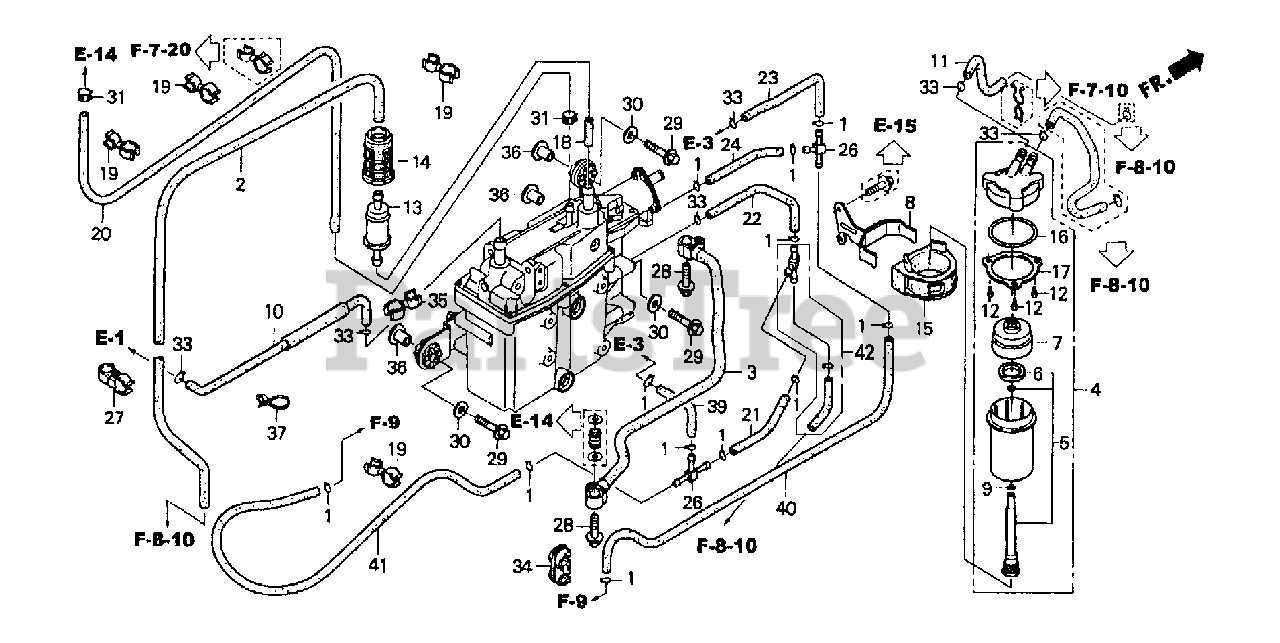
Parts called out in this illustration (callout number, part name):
1	CLIP, TUBE
2	TUBE B, AIR VENT
3	HOSE, FUEL
4	SEPARATOR ASSY., WATER
5	CUP, WATER SEPARATOR
6	FLOAT
7	BUFFER, PLATE
8	STAY, WATER SEPARATOR
9	O-RING
10	TUBE, FUEL (D)
11	TUBE E, FUEL
12	SCREW, PAN (5X12)
13	FILTER, FUEL PUMP
14	SUSPENSION, STRAINER
15	SUSPENSION, STRAINER
16	O-RING
17	PLATE
18	TUBE B, FUEL
19	CLAMP, HOSE
20	HOSE, PRESSURE REGULATOR RETURN
21	TUBE A, WATER
22	TUBE B, WATER
23	TUBE C, WATER
24	TUBE D, WATER
26	JOINT, THREE WAY
27	CLIP, SENSOR HOSE
28	BOLT, FLANGE (6X25)
29	BOLT, FLANGE (8X35)
30	WASHER, PLAIN (8MM)
31	CLAMP, TUBE (D10.7)
33	CLIP, TUBE (B12)
34	CLAMP, FUEL TUBE
35	CLAMP (6MM-12MM)
36	COLLAR (8.3X14.5)
36	COLLAR (8.5X14.5)
37	CLIP, TUBE (135MM) (BLACK)
39	BULK HOSE, VACUUM (7X3000) (7X100)
40	BULK HOSE, VACUUM (7X3000) (7X550)
41	BULK HOSE, VACUUM (7X3000) (7X690)
42	JOINT SET, THREE WAY
